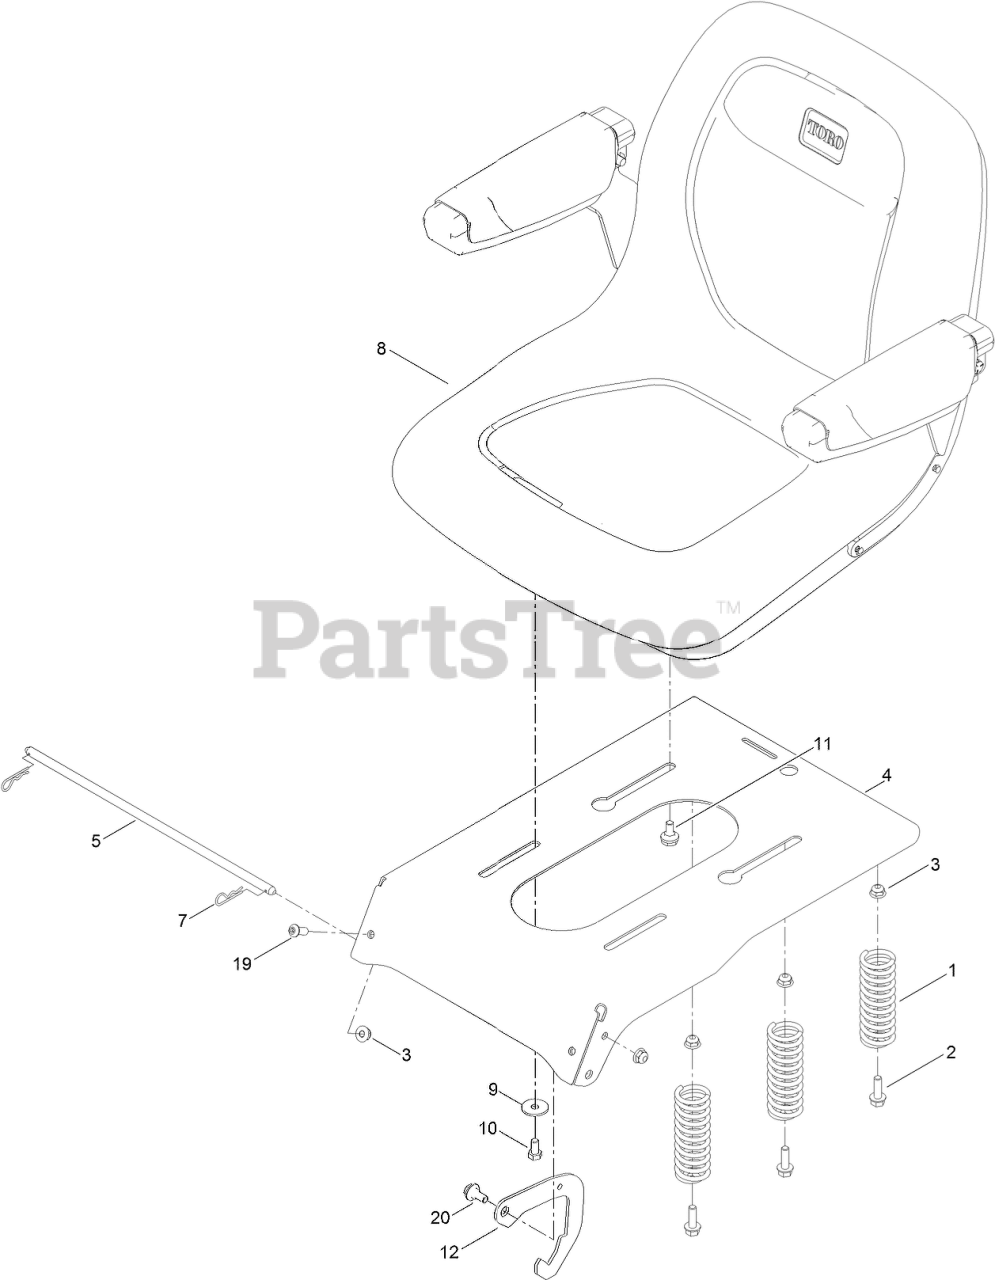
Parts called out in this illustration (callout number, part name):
1	SPRING-COMPRESSION
2	SCREW-HHF
3	NUT-HF, NI
4	PAN-SEAT
5	ROD-PIVOT, NARROW
7	PIN-COTTER
8	SEAT-18 INCH
9	WASHER-PIVOT
10	SCREW-HH
11	BOLT-SHOULDER,HFH
12	SPACER-WEIGHT
19	SCREW-HSBH
20	SCREW-SHOULDER
